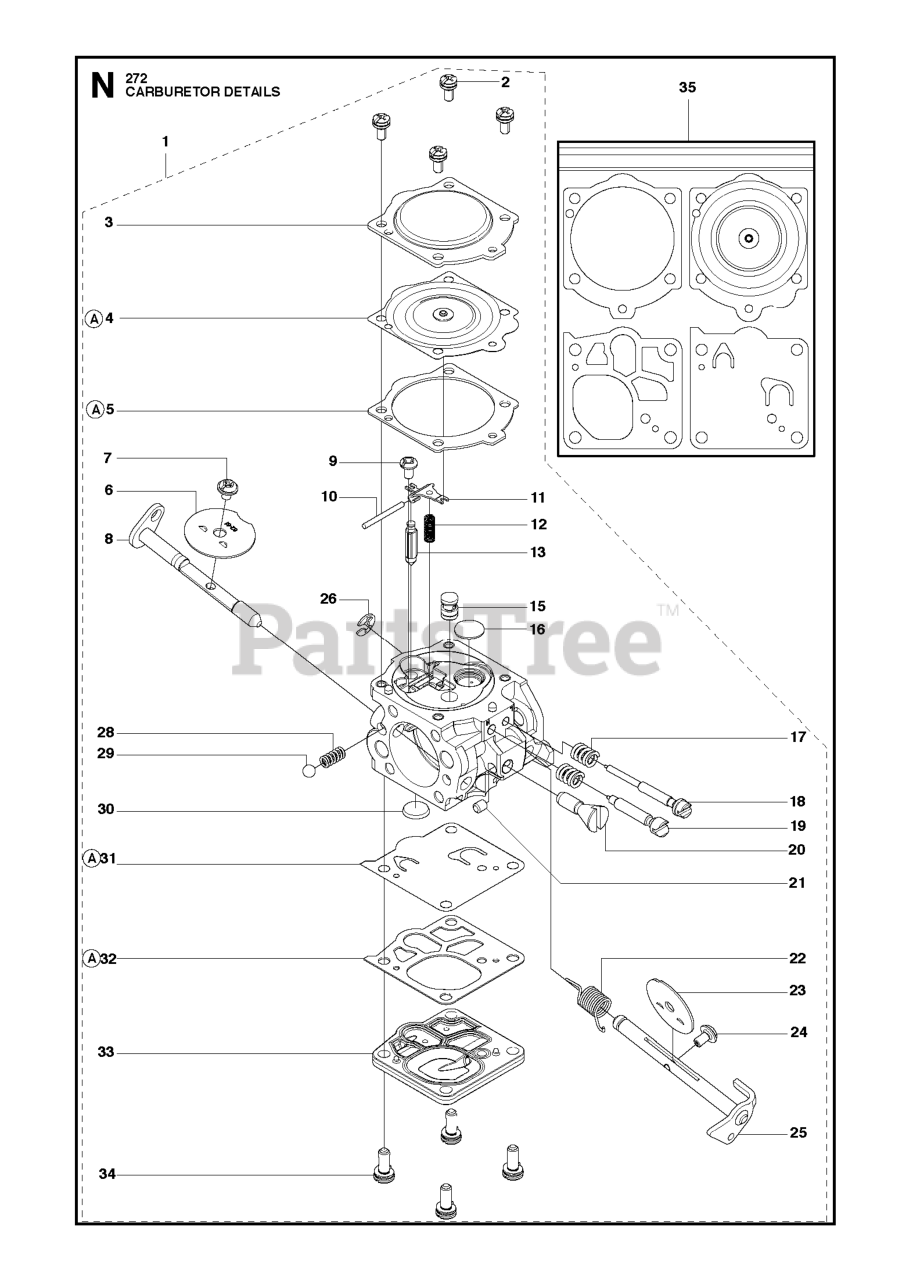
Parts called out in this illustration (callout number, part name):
2	VALVE STEM LT
3	RIM.ASM.8X5.FRONT.SILVER
4	TUBE.16X6.5/7.5-8
5	TIRE HEAVY DUTY
6	FITTING LT
7	BEARING T
8	CAP, AXLE BLK
9	TIRE HEAVY DUTY
10	TUBE.23X9.5-12
11	RIM.ASM.12X7.REAR.SILVER
